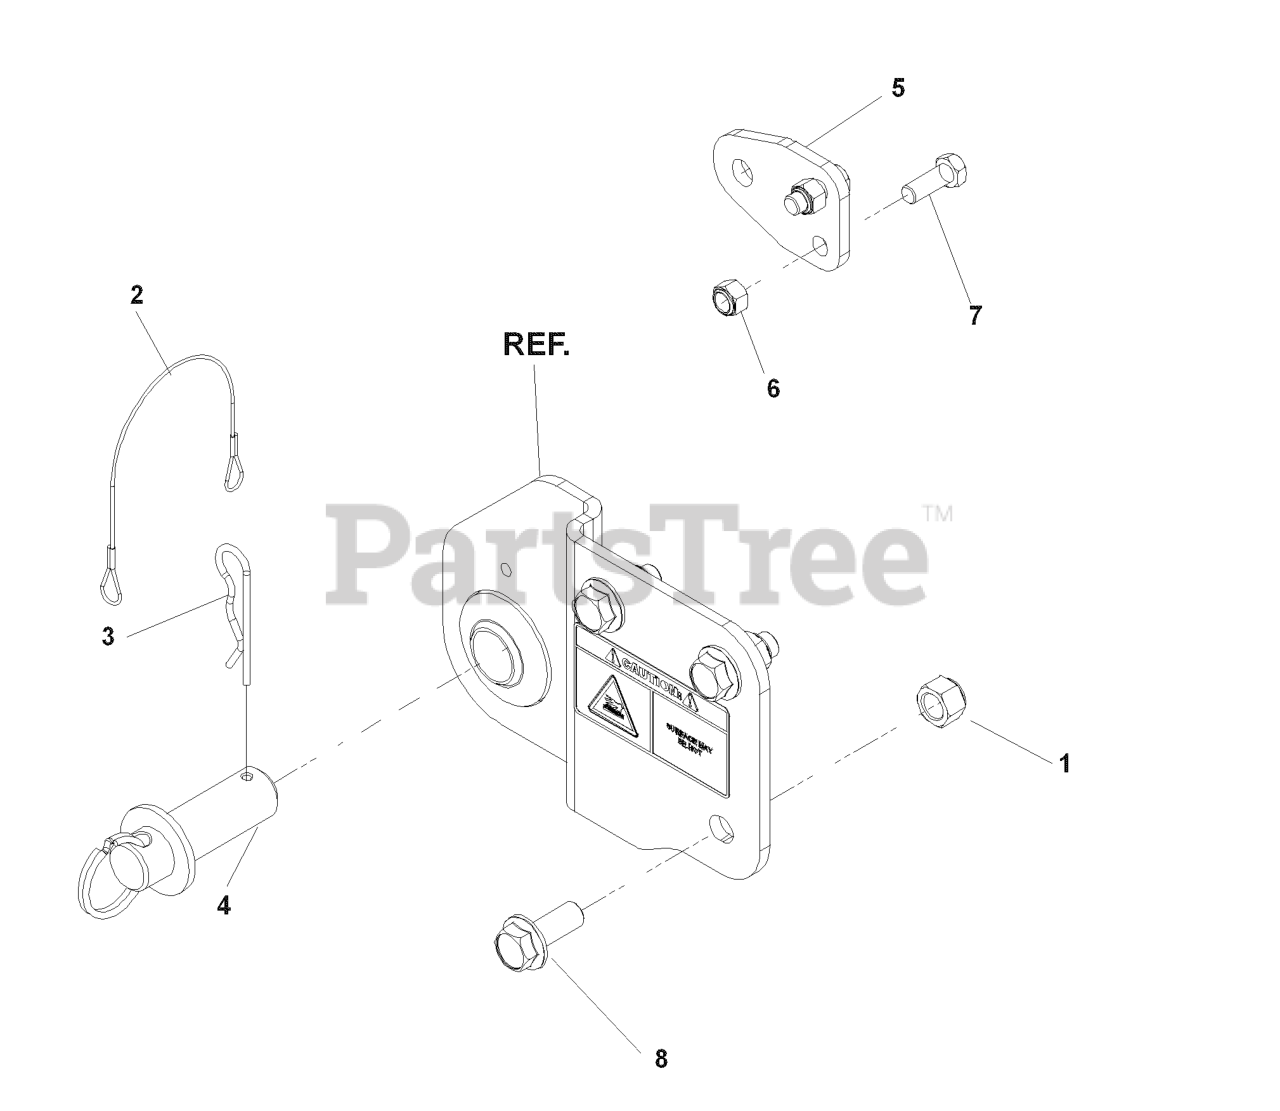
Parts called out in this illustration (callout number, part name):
1	NUT 1/2-13 HEX NYLOC ZD
5	SUPPORT BRACKET
6	NUT 3/8-16 NYLOC
7	HCS 3/8-16X1.GRD.5.ZD
8	HCS 1/2C X 1 1/4 SERRATED HEAD
